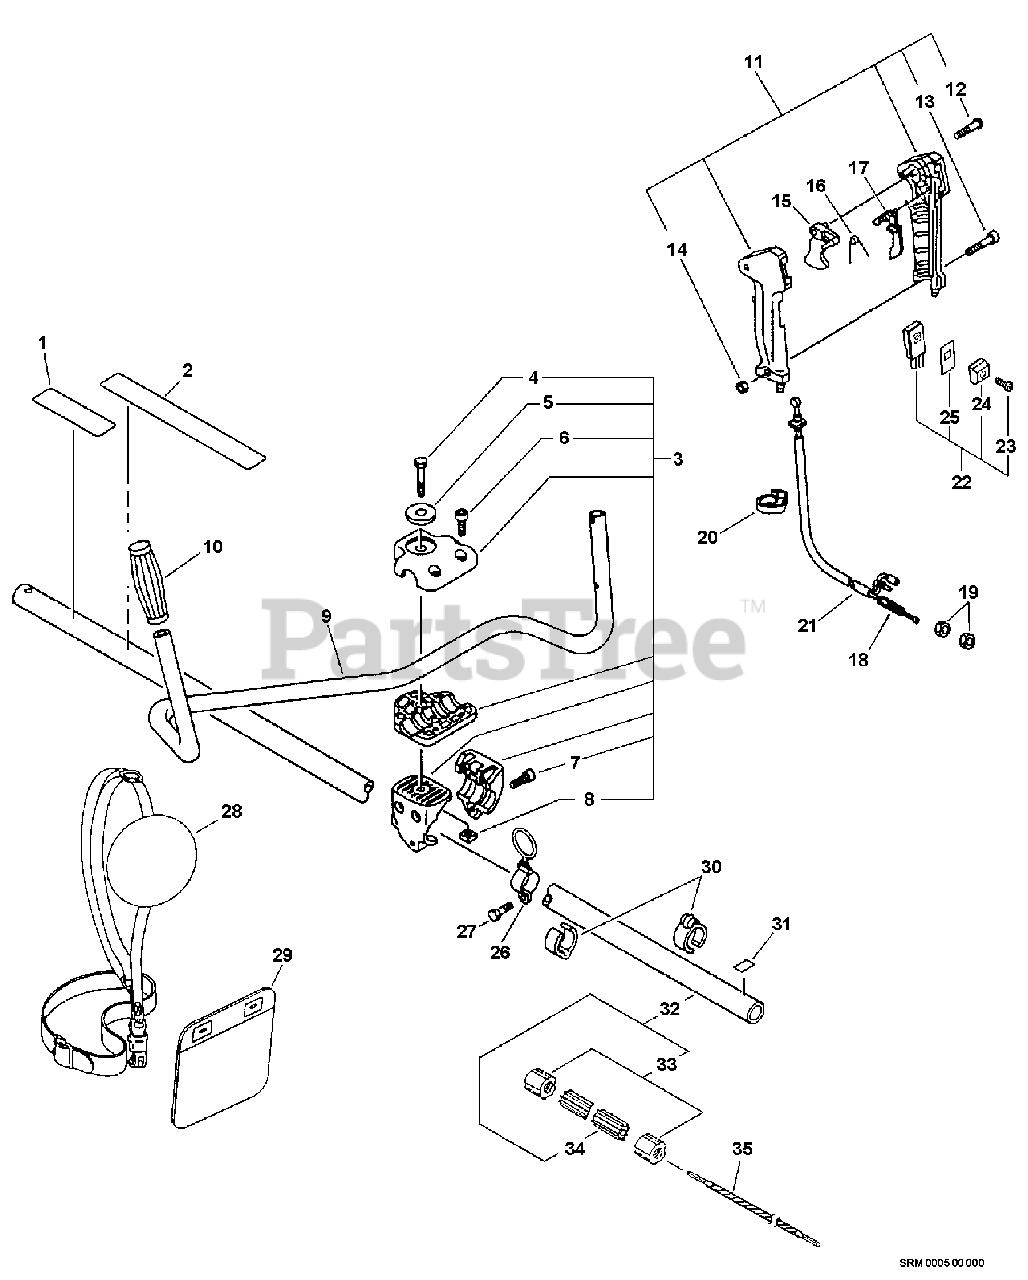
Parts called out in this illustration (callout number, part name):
1	LABEL - CAUTION -- SPANISH
2	LABEL - CAUTION
3	HANDLE BRACKET KIT
4	BOLT - 8X55
5	WASHER - 8
6	SCREW - 5X20
7	SCREW - 5X30
9	HANDLE - FRONT
10	GRIP, HANDLE - LEFT
11	THROTTLE CONTROL ASSY
12	SCREW - 3X25
13	SCREW - 5X30
15	TRIGGER, THROTTLE
16	SPRING, LOCKOUT LEVER
17	LOCKOUT, THROTTLE
18	CABLE, THROTTLE
21	TUBE, PROTECTIVE - CORRUGATED
22	IGNITION SWITCH ASSY
23	SCREW - 3X10
24	KNOB, SWITCH - ORANGE
25	COVER, SWITCH - STOP
26	HANGER KIT
27	BOLT - 5X12
28	SHOULDER STRAP ASSY
29	CUSHION
31	LABEL - ALIGNMENT
32	MAIN PIPE ASSY
34	LINER - FLEXIBLE
35	DRIVESHAFT - FLEXIBLE
36	LOCKING TOOL
37	T-WRENCH - 17X19mm
